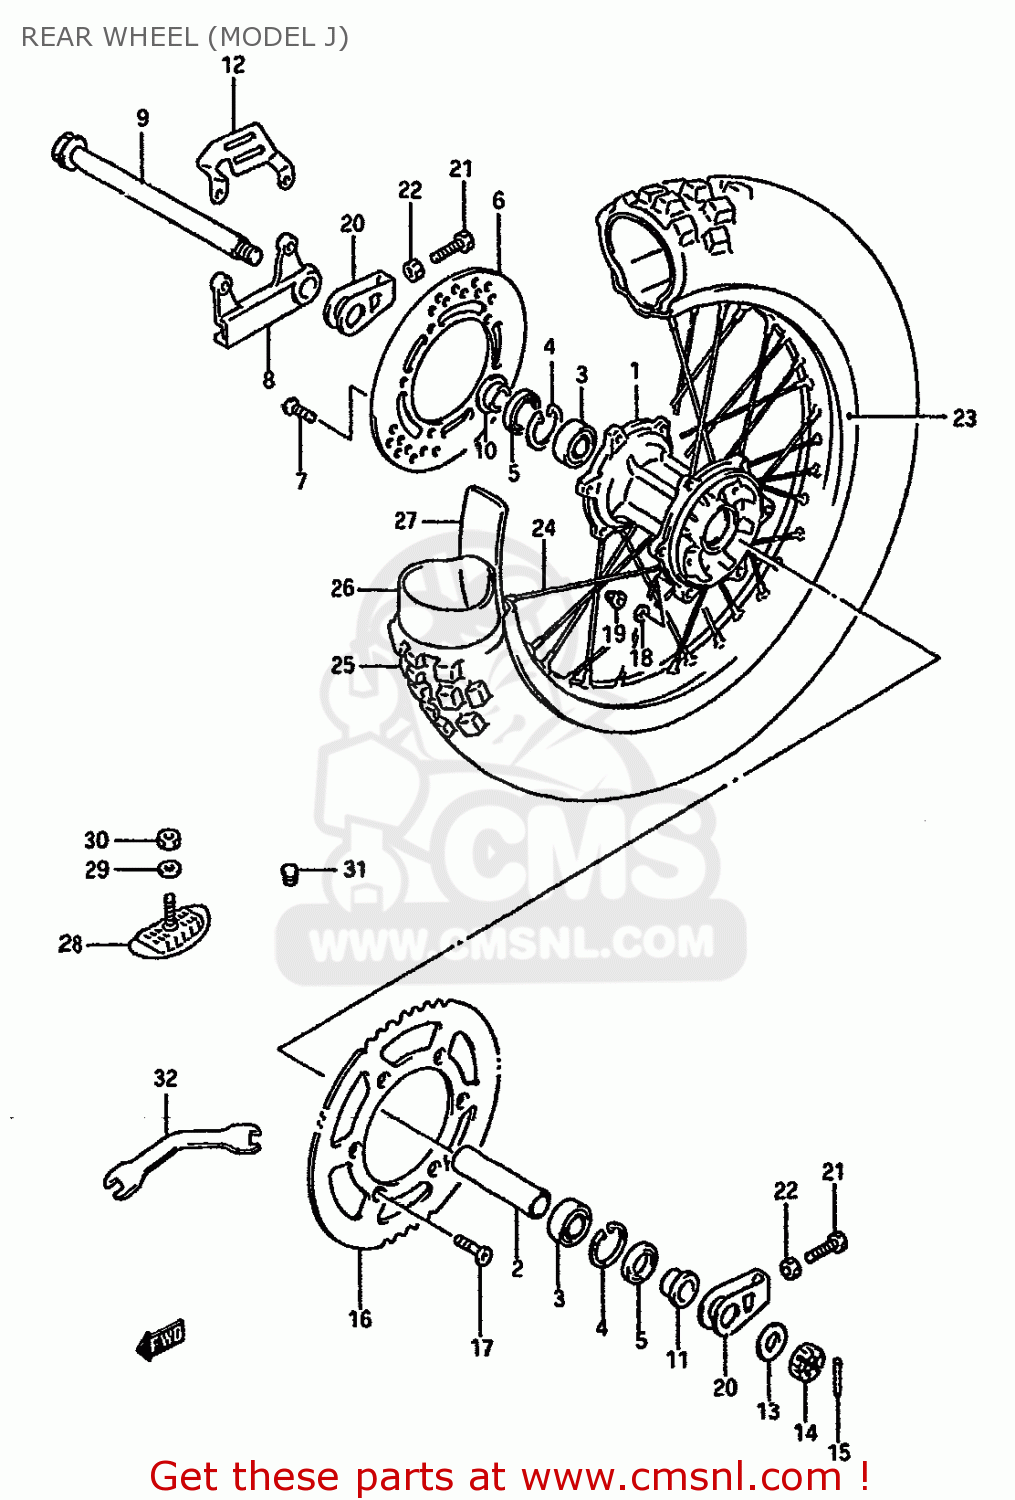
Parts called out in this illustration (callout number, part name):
1	HUB,REAR WHEEL
2	SPACER,RR HUB BEARING
3	BEARING
4	CIRCLIP,14MM
5	OIL SEAL
6	DISC,REAR BRAKE
7	SCREW
8	BRACKET,REAR CALIPER
9	AXLE,RR
10	SPACER,RR AXLE,R
11	SPACER,REAR AXLE,LEFT
12	GUARD,REAR CALIPER
13	WASHER (19X32X3.2)
14	NUT 18MM
15	PIN,COTTER
16	SPROCKET,REAR
17	SCREW(8X33.5)
18	WASHER
19	NUT
20	ADJUSTER COMP,CHAIN
21	BOLT L:50
22	NUT
23	RIM,REAR WHEEL (1.85X18)(A
24	SPOKE SET,REAR WHEEL
25	TIRE
26	TUBE ASSEMBLY,WHEEL,INNER
27	PROTECTOR
28	STOPPER,BEAD
29	WASHER
30	NUT 8MM
31	CAP(OD:12)
32	SPANNER,OPEN
